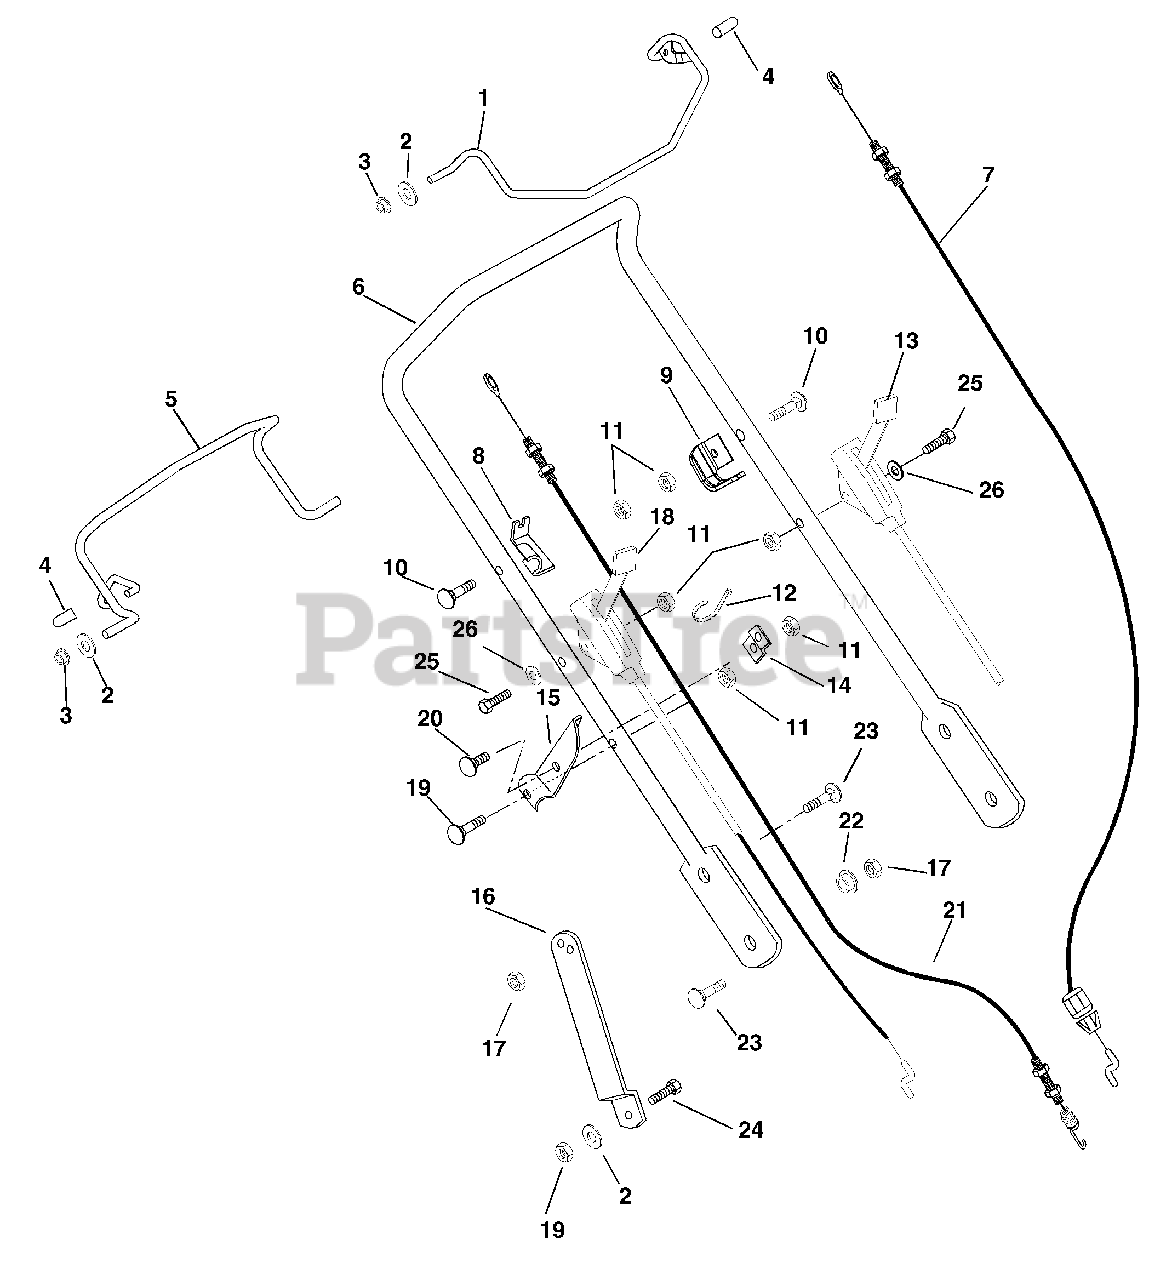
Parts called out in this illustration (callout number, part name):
1	Engine Bail Weldment
2	Washer-Flat-Steel .325 x .688 x .065
3	Bushing-Flange .325 x .688 x .560
4	Cap, Vinyl .25 I.D.
5	Traction Bail
6	Handlebar, Self-Proppelled
7	Engine Control Cable
8	Cable Anchor-Right Hand
9	Cable Anchor-Left Hand
10	Bolt-Round Head Square Neck .25-20 x 1.25
11	Nut-Locking-Center .25-20
12	Cable Tie
13	Throttle Cable
14	Brace-Speed Control
15	Bracket-Speed Control
16	Handlebar Bracket
17	Nut-Locking Center .31-18
18	Cable-Gear Shift
19	Bolt-Round Head Square Neck .25-20 x 1.38
20	Bolt-Round Head Square Neck .25-20 x .50
21	Traction Cable
22	Shoulder Spacer
23	Bolt-Round Head Square Neck .31-18 x .75 Grade 5
24	Bolt-Hex .31-18 x .75 Grade 5
25	Bolt-Hex .25-20 x 1.75 Grade 5
26	Washer-Flat-Steel .250 x .562 x .049
